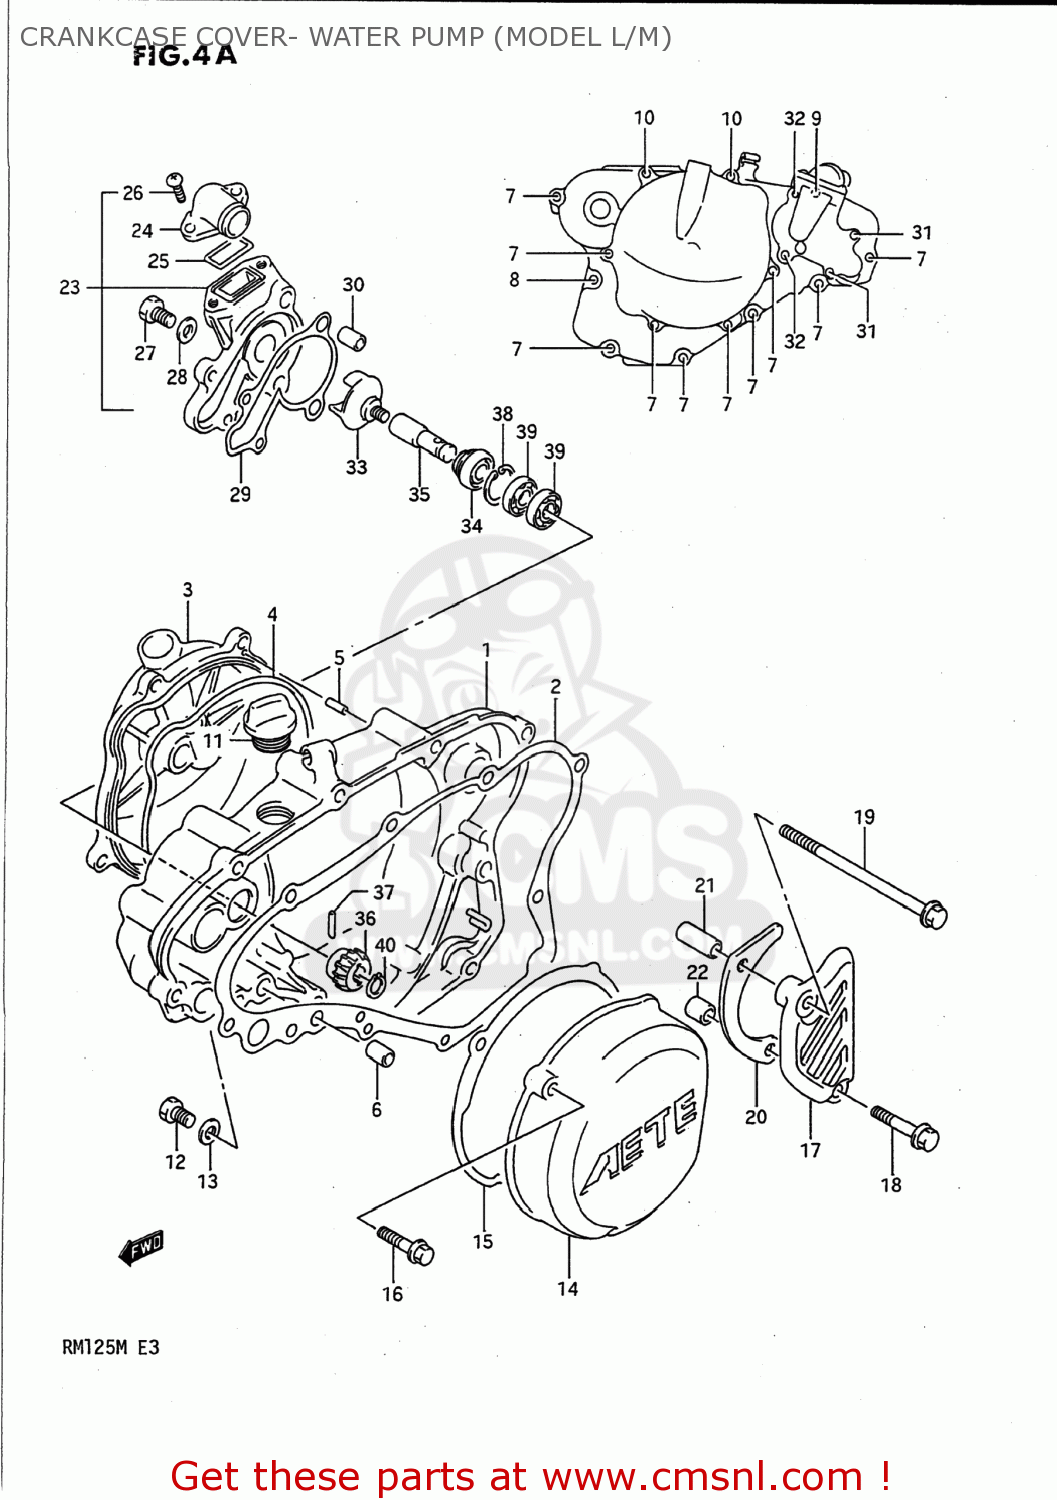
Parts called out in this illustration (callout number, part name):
1	COVER,CLUTCH
2	GASKET,CLUTCH COVER (NAS)
3	COVER,CLUTCH,OUTER
4	O RING,CLUTCH COVER OUTER
5	PIN
6	PIN
7	BOLT
8	BOLT
9	BOLT
10	BOLT
11	PLUG SET
12	SCREW(6X10)
13	GASKET(6.2X11X1).2 (NAS)
14	COVER,MAGNETO
15	GASKET,MAGNETO COVER (MCA)
16	BOLT
17	COVER,SPROCKET
18	BOLT
19	BOLT(6X105)
20	PLATE,FR CHAIN GUIDE
21	SPACER(6.5X10.5X25)
22	SPACER(6.5X10.5X12)
23	CASE ASSEMBLY,WATER PUMP
24	CONNECTOR
25	O RING,WATER PUMP CONNECTOR
26	SCREW
27	BOLT,BLEEDER
28	GASKET (NAS)
29	GASKET,WATER PUMP CASE (NAS)
30	PIN
31	BOLT
32	BOLT
33	IMPELLER,WATER PUMP
34	SEAL,WATER PUMP OIL
35	SHAFT,WATER PUMP
36	GEAR,WATER PUMP DRIVEN
37	PIN(3X13.8)
38	CIRCLIP
39	BEARING
40	CIRCLIP
